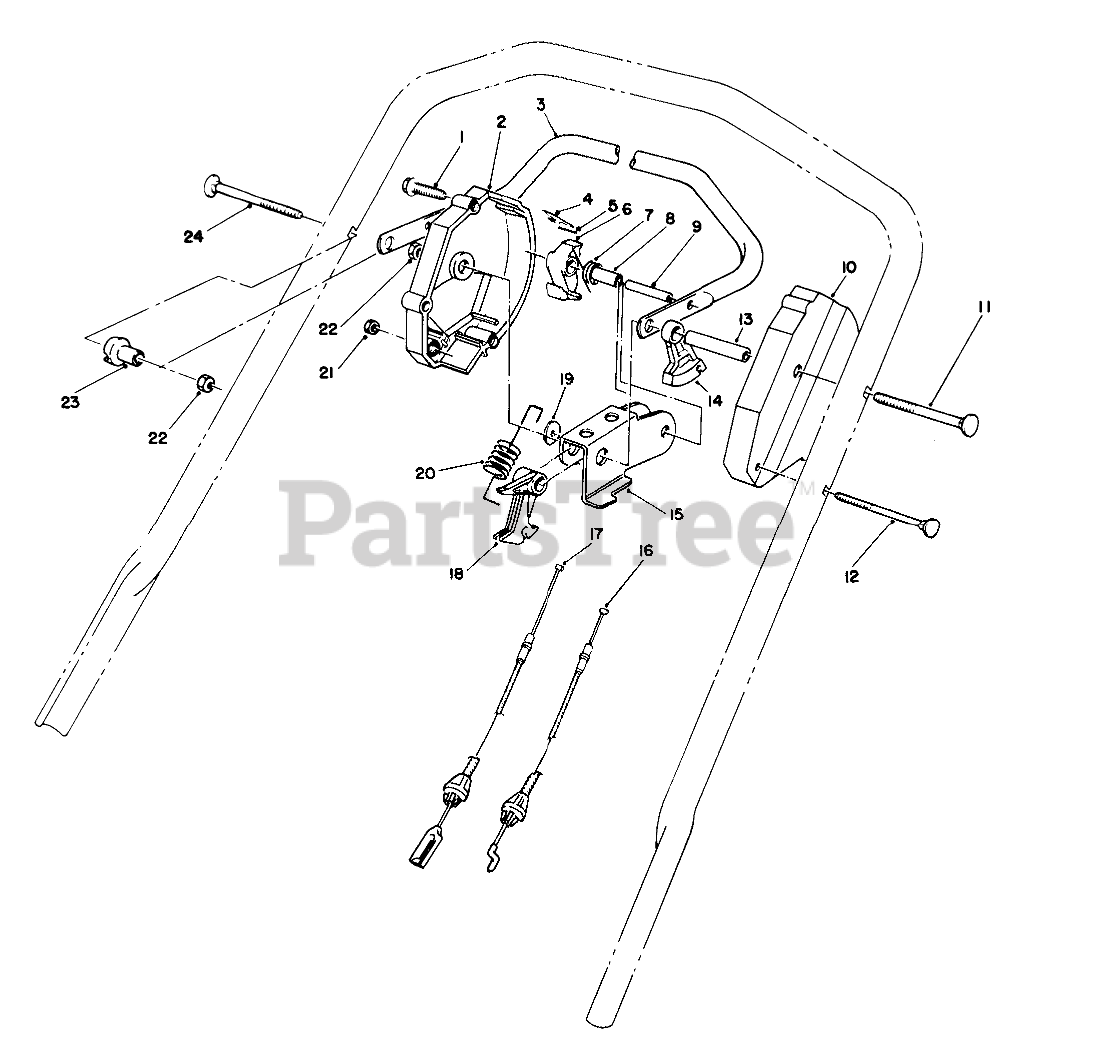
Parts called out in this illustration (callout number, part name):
1	SCREW-HWHTF
2	Housing-Control
3	Bar-Control
4	SPRING-LEAF
5	PIN-INSERT
6	HOOK-CONTROL
7	SPRING-TORSION
8	SPACER
9	PIN-ROLL, SLOTTED
10	HOUSING-CONTROL, LH
11	Screw-Handle
12	HANDLE SCREW
13	TUBING-SPACER
14	LEVER-TRACTION
15	ROCKER
16	TRACTION CABLE
17	BBC CABLE ASSEMBLY
18	LEVER-CABLE
19	WASHER-NYLON
20	SPRING-DETENT
21	NUT-HEX
22	NUT-LOCK, NI
23	SPACER-SUPPORT
24	SCREW-HANDLE
